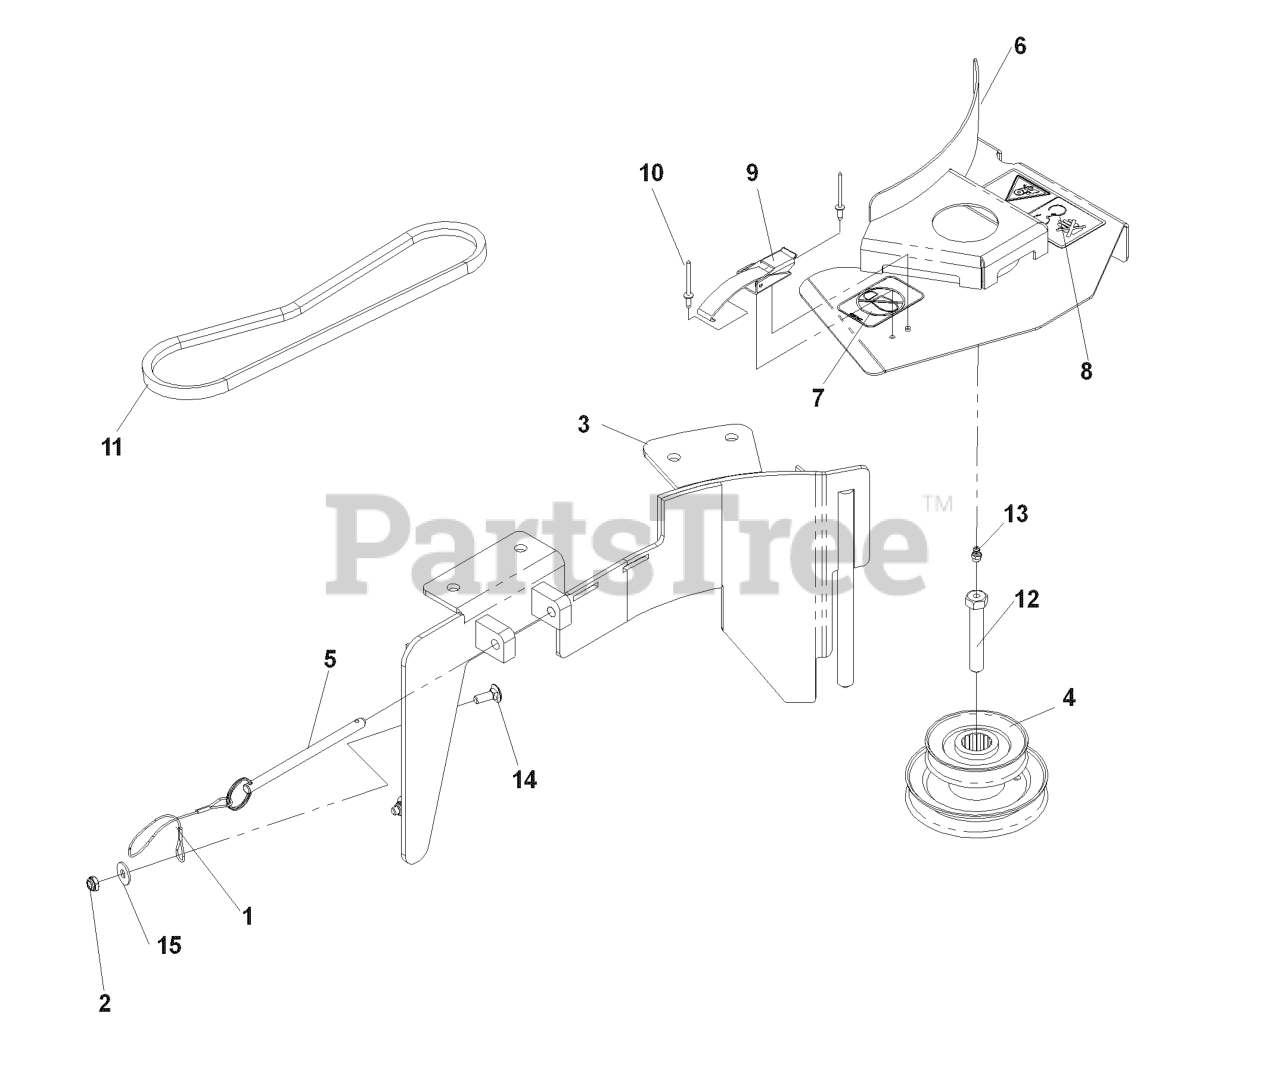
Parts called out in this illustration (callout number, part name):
2	JAM NUT 1/4C (2 2 PW01)
3	BLOWER DECK PLATE
4	42/48 LG DBL HEX STACK PULLEY
6	BELT SHIELD ASSY, 42"
7	DECAL, NO STEP
8	DECAL, BELT DRIVE
9	DRAW LATCH
10	RIVET, BLIND, 5/32 DIA
12	HCS, 7/16-20 X 2 1/2, GR8
13	ZERK
14	RHSNB 1/4C X 3/4
15	WASHER 1/4 FLAT
